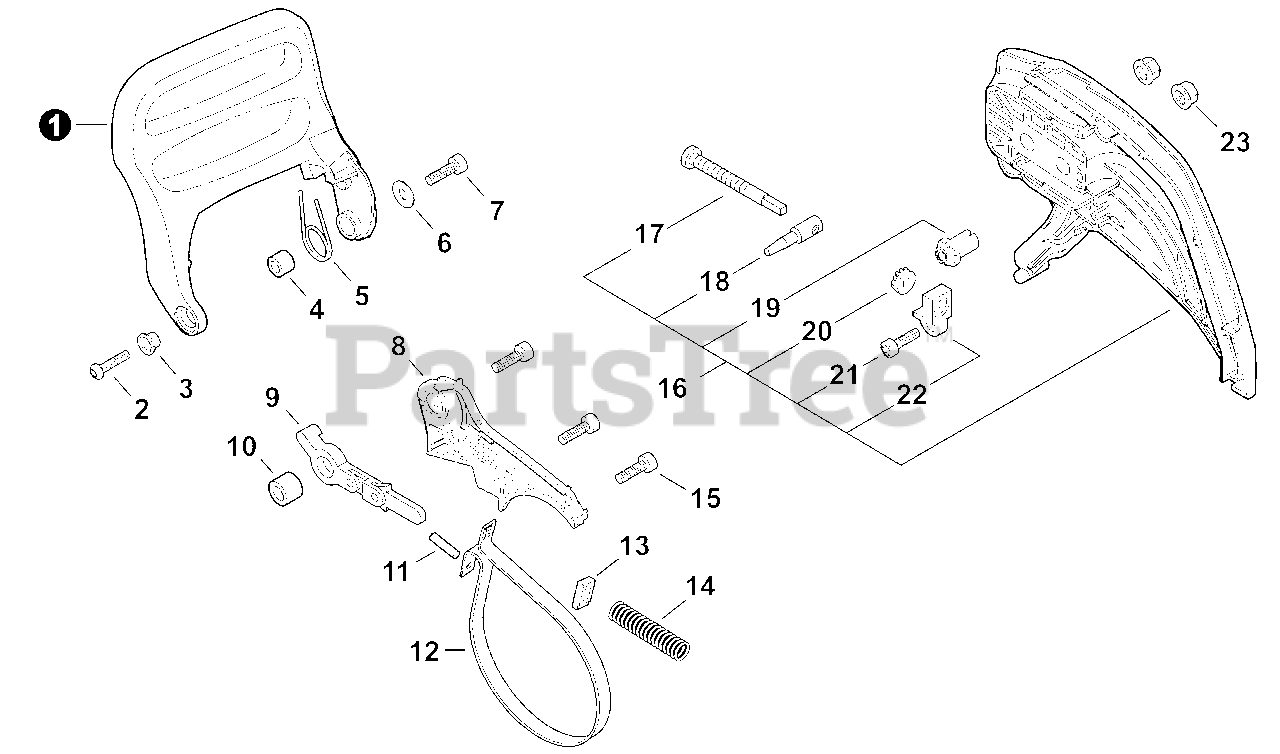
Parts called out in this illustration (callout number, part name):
1	LEVER, BRAKE
2	BOLT, TORX 5×20
3	COLLAR 10
4	SPACER 8×12×9
5	SPRING, TORSION
6	WASHER 4.2×16.5×1
7	BOLT, TORX 4×20
8	COVER, BRAKE
9	CONNECTOR, BRAKE
10	SPACER 8×12×9
11	PIN, SPRING 3x-9.8
12	BAND, BRAKE
14	SPRING, COMPRESSION
15	BOLT, TORX 4×12
16	COVER ASSY, CLUTCH
17	SCREW, CHAIN TENSION
18	TENSIONER, CHAIN
19	GEAR, BEVEL
20	GEAR, BEVEL
21	BOLT, TORX 4×12
22	COLLAR 8
23	NUT, FLANGE M8×1.25
